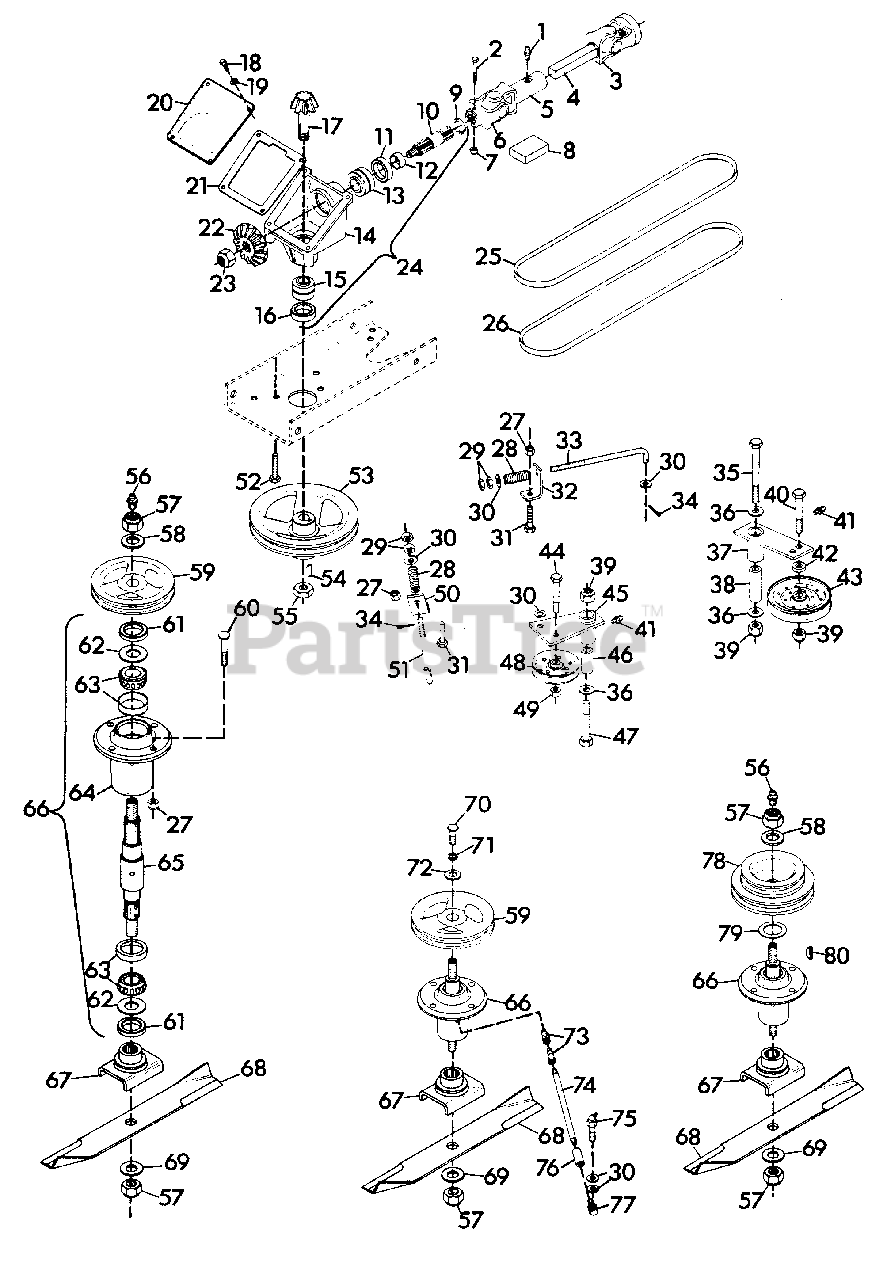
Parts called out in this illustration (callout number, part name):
1	Fitting, Lube 1/4-28
2	Bolt, Hex 1/4-20x2.25
3	Yoke
4	Shaft, Prop. Sq. Bar
5	U-Joint, Female
7	Nut, Lock 1/4-20
8	Kit, Repair U-Joint
9	Ring, Retaining 1.000 Shaft
10	Shaft
11	Seal, Oil
12	Spacer
13	Assembly, Bearing
14	Casting, Gear Box
15	Assembly, Bearing
16	Seal, Oil
17	Shaft, Gear Pinion
18	Bolt, Hex 1/4-20x.50
19	Washer, Lock 1/4 Reg.
20	Cover, Gear Housing
21	Gasket, Gear Housing
22	Gear, Bevel
23	Nut, Lock 3/4-10
24	Assembly, Drive
25	Belt, "A"
26	Belt, "B"
27	Nut, Lock 3/8-16
28	Spring, Comp. 1x.78x338
29	Nut, Hex 3/8-24
30	Washer, Flat .406x.812x.065
31	Bolt, Hex 3/8-16x1.00
32	Support, Spring "B"
33	Rod, Idler
34	Pin, Cotter .06x1.00
35	Bolt, Hex 1/2-13x3.75
36	Washer, Flat .500x1.250x.083
37	Weldment, Idler Pivot "B"
38	Spacer, .850x.546x2.50
39	Nut, Lock 1/2-13
40	Bolt, Hex 1/2-13x2.00
41	Fitting, Lube 1/4-28
42	Spacer, .516x.875x.300
43	Pulley, Flat Idler
44	Bolt, Hex 3/8-16x1.75
45	Weldment, Idler Pivot "A"
46	Spacer, .850x.546x2.18
47	Bolt, 1/2-13x3.50 Rd Hd Sq Nk
48	Sheave, Idler
49	Nut, Lock 3/8-16
50	Support, Spring "A"
51	Rod, Idler
52	Bolt, Hex 1/2-13x1.00
53	Pulley, Gear Box
54	Key, Woodruff 3/16x5/8 No. 61
55	Nut, Jam 3/4-10 Hex Heavy
56	Fitting, Lube 1/8
57	Nut, Lock 5/8-11
58	Washer, Flat .687x1.312x.122
59	Pulley
60	Bolt, 3/8-16x1.375 Rd Hd Sq Nk
61	Seal, Steel(Right and Center Spindles)
61	Seal, Steel(Left Spindle)
62	Washer, Flat .975x1.970x.030(Right and Center Spindles)
62	Washer, Flat .975x1.970x.030(Left Spindle)
63	Assembly, Bearing
64	Housing, Bearing(Left and Right Spindle)
64	Housing, Bearing(Center Spindle)
65	Shaft, Spindle(Right Spindle)
65	Shaft, Spindle(Center Spindle)
65	Shaft, Spindle(Left Spindle)
66	Assembly, Spindle(Right Spindle)
66	Assembly, Spindle(Center Spindle)
66	Assembly, Spindle(Left Spindle)
67	Weldment, Blade Cradle
68	Blade
69	Washer, Flat .656x1.312x.095
70	Bolt, Hex Special 1/2-13x1.34
71	Washer, Lock 1/2 Reg.
72	Washer, Flat 1.38x.56 Hard
73	Elbow, Street 1/8-26(Center Spindle)
74	Nipple, Pipe 6.30
75	Fitting, Lube 65 Degree
76	Coupling, Pipe 1/8-27
77	Elbow, Adaptor 90 Degree
78	Pulley, Drive
79	Race, Bearing Thrust
80	Key, Woodruff .25x1.00 Hard #15
